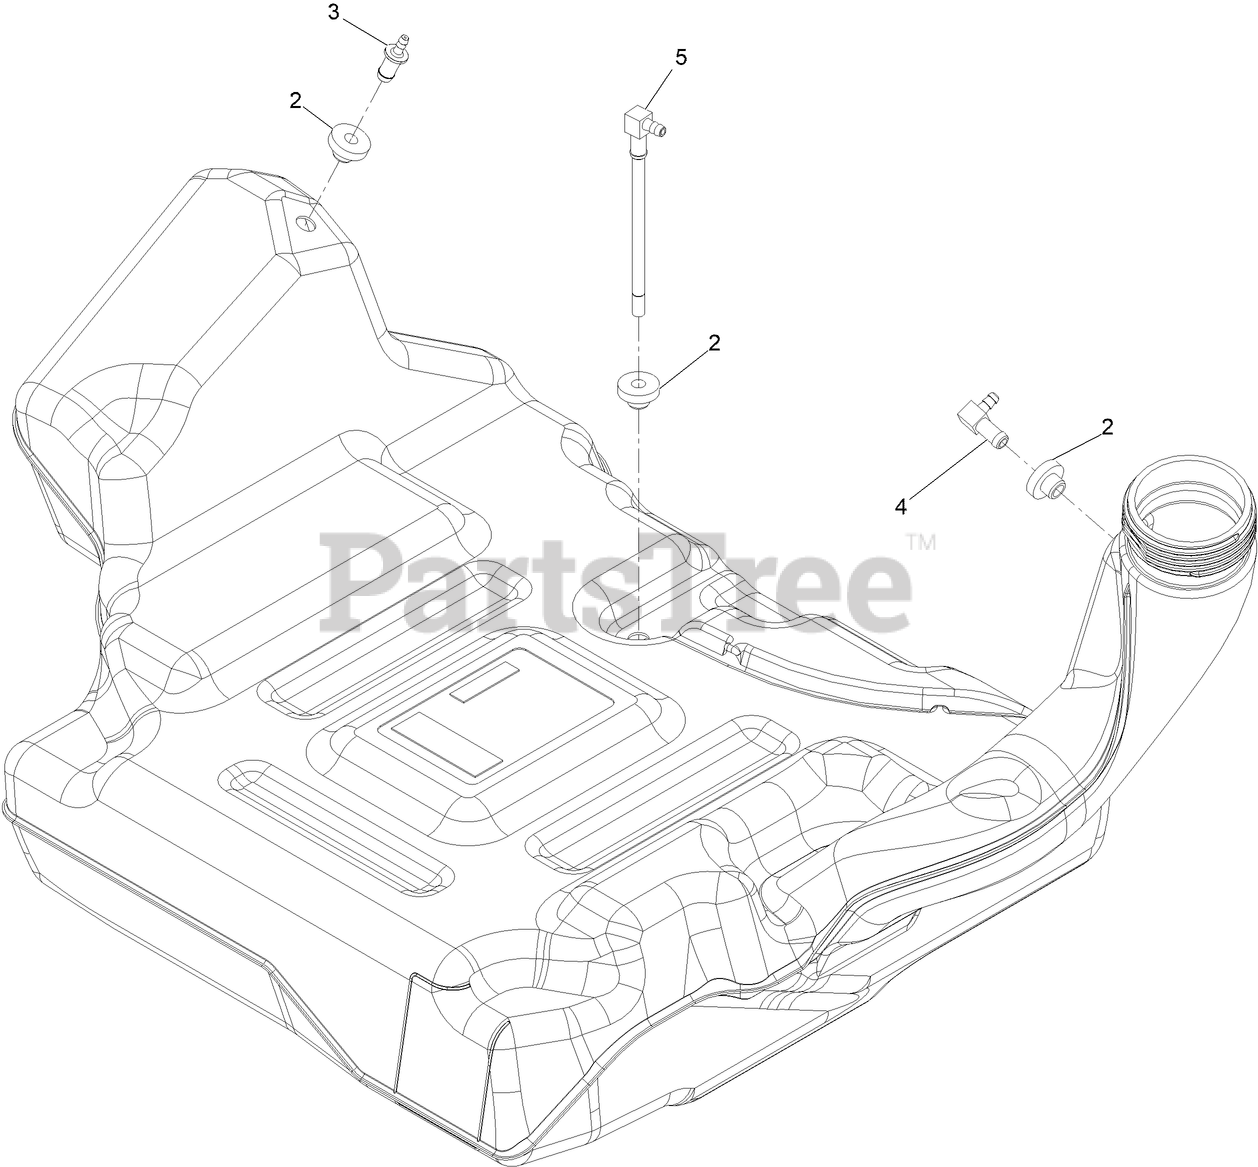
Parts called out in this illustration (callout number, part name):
2	BUSHING
3	FITTING-ORIFICE, STRAIGHT
4	FITTING-90 DEG
5	FITTING,FUEL W/LINE AND SCREEN
